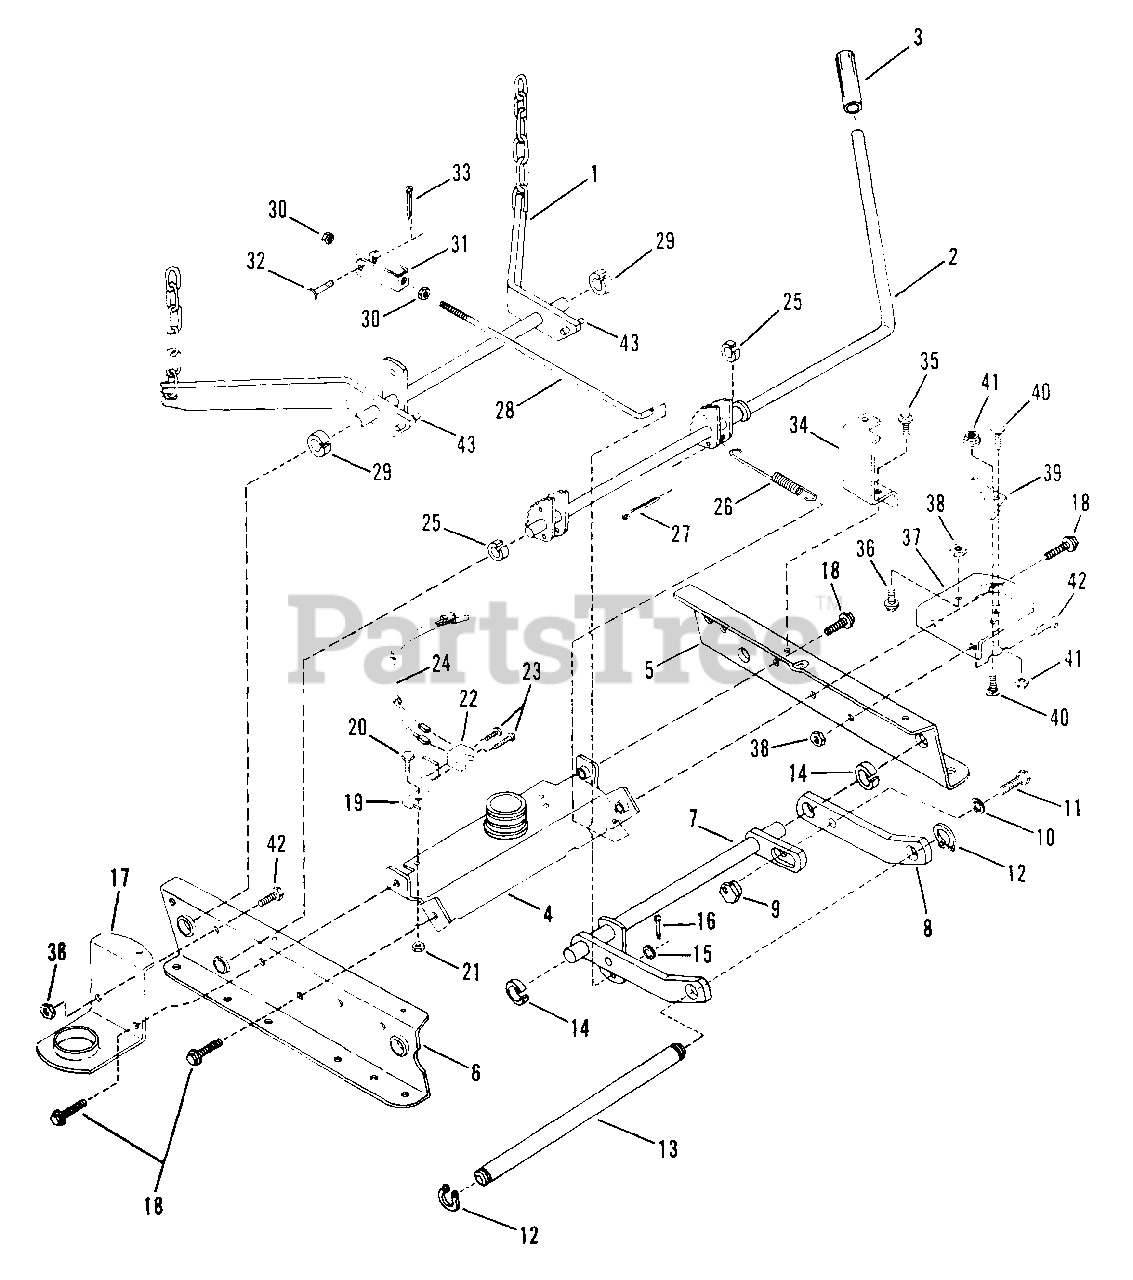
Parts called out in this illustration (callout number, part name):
1	ASSEMBLY, REAR LIFT ARM
2	CAM LIFT LEVER
3	GRIP, Cam Lift Lever
4	BRACE, Top Rail
5	RAIL, Left Hand
6	RAIL, Right Hand
7	ASSEMBLY, FRONT LIFT ARM
8	LIFT ARM, Front
9	LEVELING ACCENTRIC
10	WASHER, 3/8 Internal Tooth Lock
11	CAPSCREW, 3/8-24 x 1" Hex Head
12	RING, 5/8" External Retaining
13	SUPPORT ROD
14	RING, Red
15	WASHER, 3/8" Flat
16	COTTER-PIN, 1/8 x 3/4"
17	BRACE, Spindle, Right Hand
18	SCREW, 3/8-16 x 1" Hex Head Self-Tapping
19	BRACKET, Internal Switch
20	BOLT, 5/16-18 x 3/4" Hex Flange Lock
21	NUT, 5/16-18 Hex Flange Lock
22	SWITCH, Interlock
23	SCREW, #10-24 x 1/2" Hex Washer Self-Tap (Torx)
24	WIRE, Mower Deck
25	RING, White
26	SPRING, Cam Lift
27	COTTER-PIN, 5/32 x 1"
28	ROD, Timing
29	RING, Blue
30	NUT, 3/8-24 Hex
31	CLEVIS, Timing Rod
32	PIN, 3/8 x 1 1/16" Clevis
33	COTTER-PIN, 3/32 x 3/4"
34	BRACKET, Cover
35	SCREW, 1/4-20 x 5/8" Self-Tapping
36	CAPSCREW, 3/8-24 x 1" Hex Head
37	BRACE, Spindle, Left Hand
38	NUT, 3/8-24 Hex Lock
39	ANCHOR
40	BOLT, 5/16-18 x 3/4" Carriage
41	NUT, 5/16-18 Hex Flange Lock
42	CAPSCREW, 3/8-24 x 3/4" Hex Head
43	PIN, Roll
